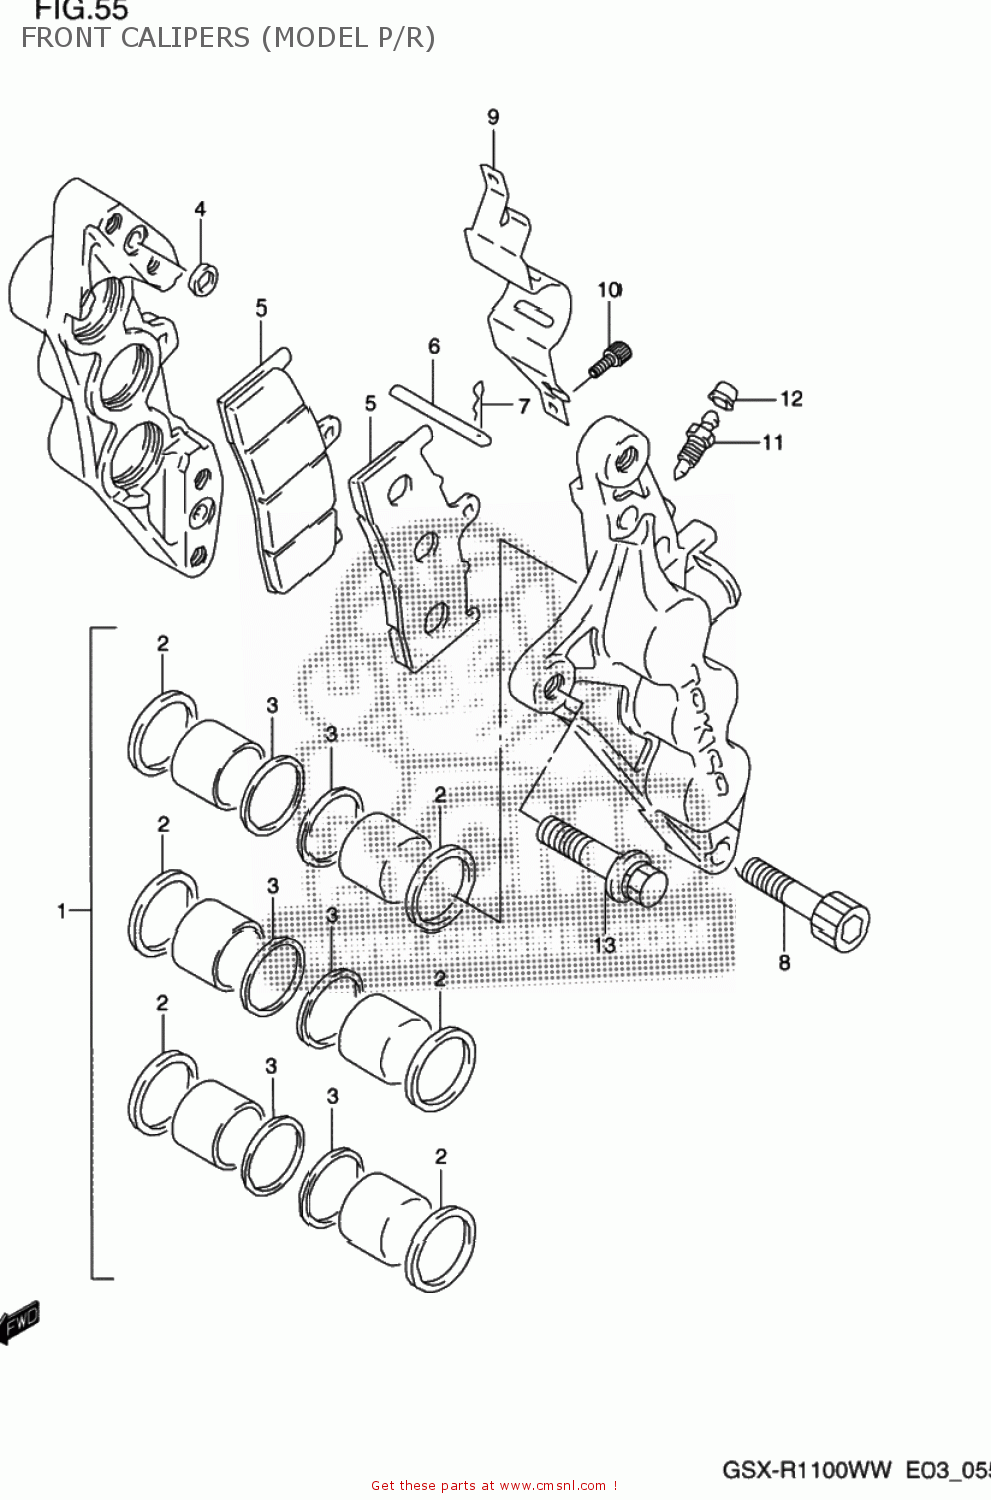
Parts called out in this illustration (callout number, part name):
1	PISTON SET
2	SEAL,PISTON
3	SEAL,WIPER
4	SEAL,JOINT
5	PAD,BRAKE
6	PIN,PAD
7	CLIP,PAD PIN
8	BOLT,CALIPER
9	COVER,CALIPER
10	SCREW
11	BLEEDER
12	CAP,BREATHER
13	BOLT
